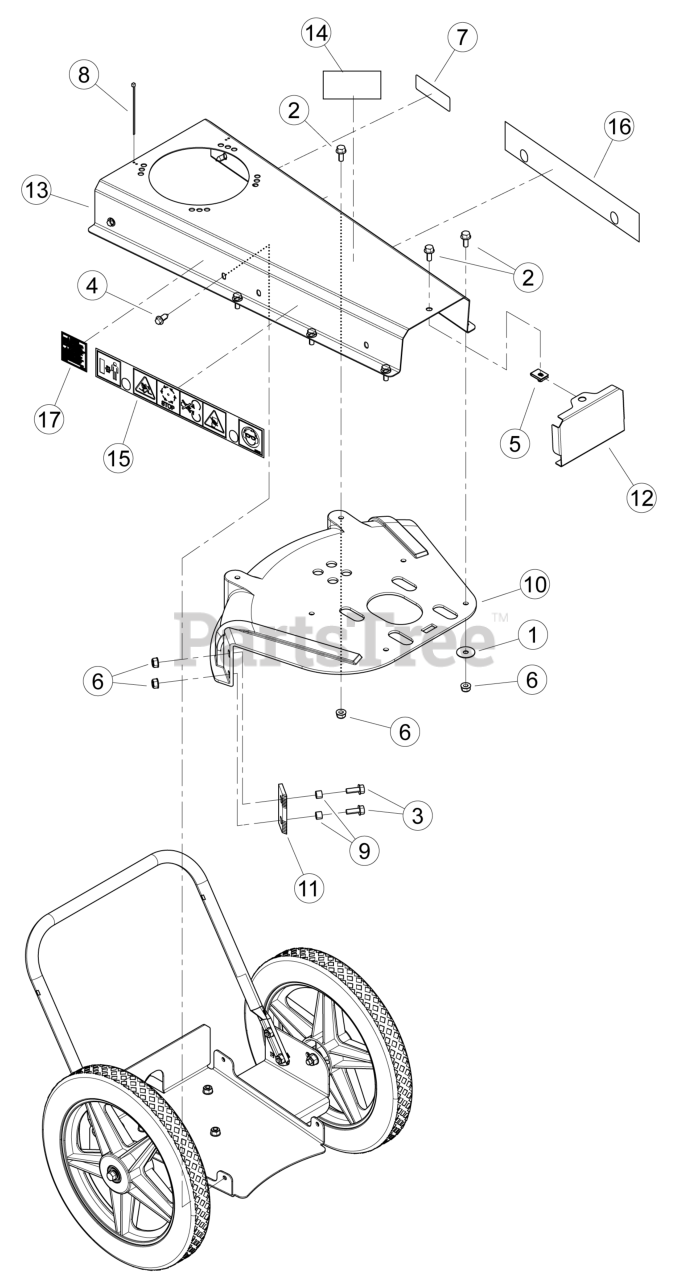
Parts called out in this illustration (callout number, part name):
1	WASHER, 5/16" FENDER ZP
2	BOLT, 5/16 × 3/4 FLANGE NC
3	BOLT, 5/16 × 7/8 FLANGE NC
4	SCREW, 11/32-12 × 7/8 FLANGE T-AB
5	NUT 5/16"-18 TINNERMAN U-TYPE
6	NUT, 5/16-18 NYLOCK FLANGE
7	DECAL, SERIAL NUMBER
8	STRAP, 4 IN BLACK
9	SPACER, PLASTIC TRIMMER SHIELD
10	SHIELD, TRIMMER
11	KNIFE, RECTANGULAR SHREDDING
12	COVER, METAL HW TRIMMERS
13	ASSEMBLY, BODY WITH DECALS
14	DECAL, MODEL ECHO WT-1610
15	DECAL, HW SAFETY INFORMATION
16	DECAL, HW MAINTENANCE INFORMATION
17	DECAL, SPARK ARRESTOR
